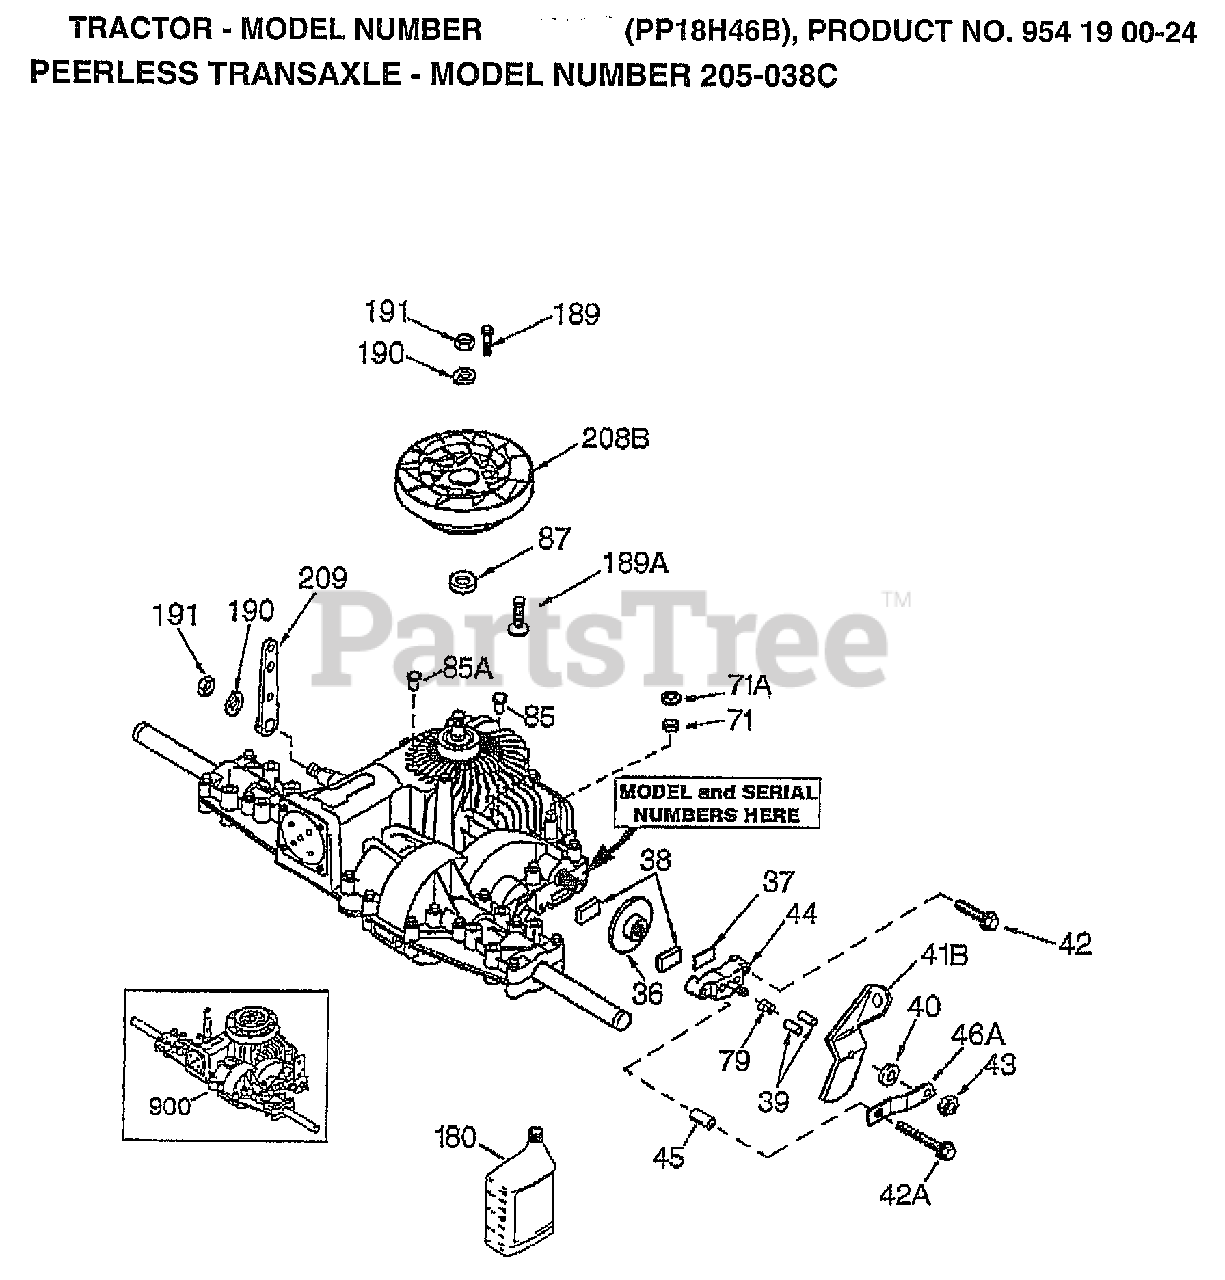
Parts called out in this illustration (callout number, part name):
37	PLATE BRAKE PAD
41B	BRAKE LEVER
42A	SCREW, 1/4-20 X 2-1/4
43	LOCKNUT 5/16-24
44	HOLDER BRAKE PAD
46A	BRAKE LEVER BRACKET
71	SEAL SQUARE CUT
85	OIL FILL PLUG
85A	TUBE PLUG, 3/8"
180	GEAR OIL 80W90
189	DRIVE SCREW
208B	FAN/COUPLING
209	CONTROL LEVER
900	REPLACEMENT 205-038C TRANSAXLE
